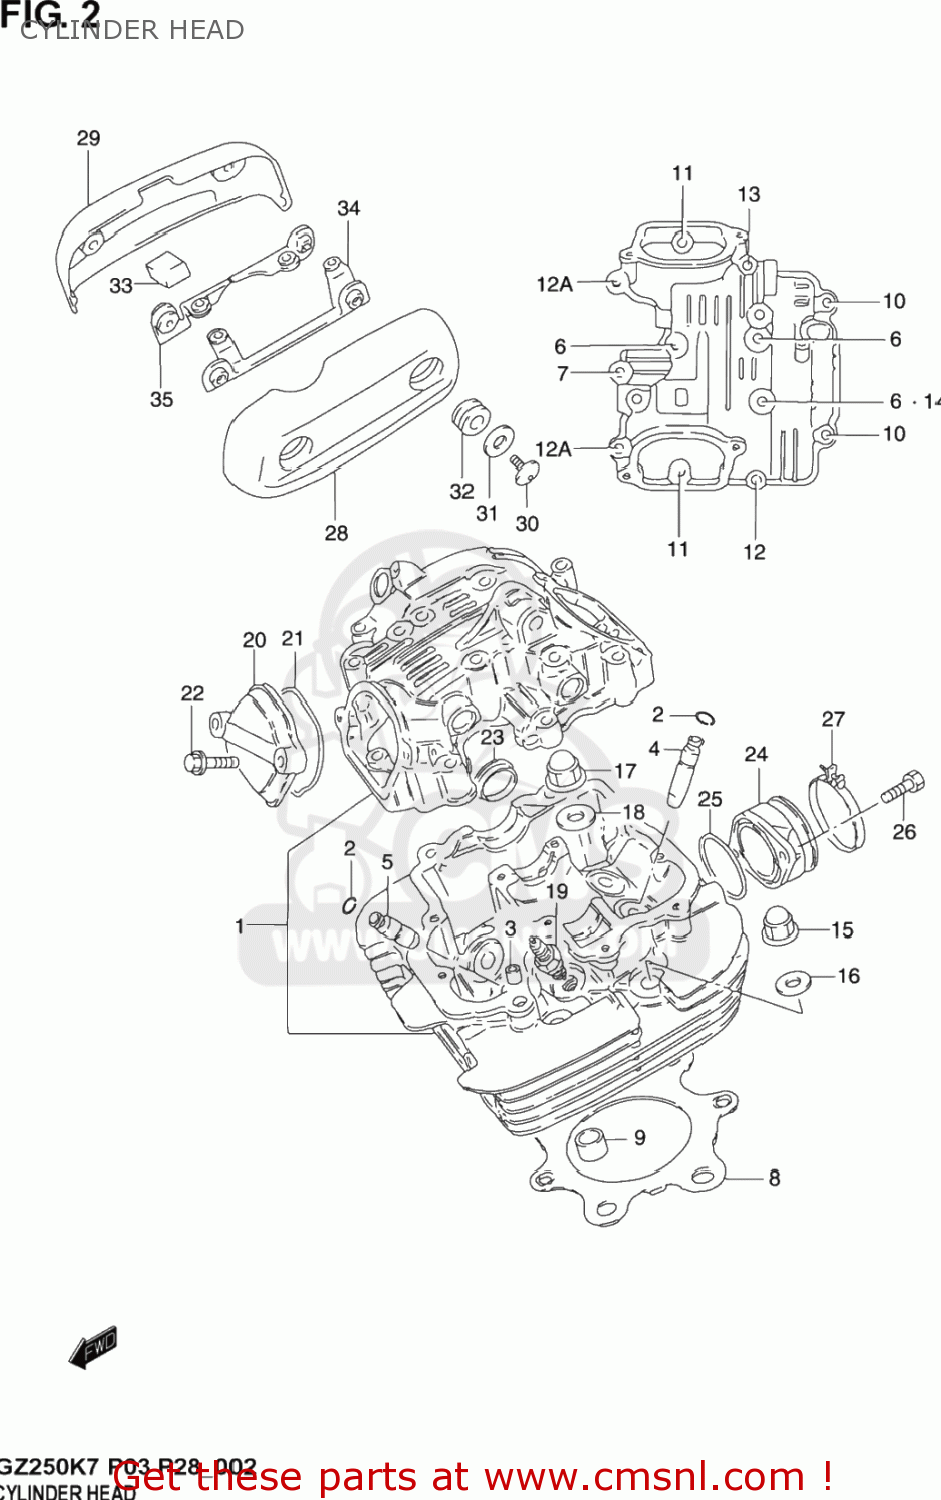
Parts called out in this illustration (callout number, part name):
1	HEAD ASSY,CYLINDER
2	RING,SNAP
3	PIN(6.2X8X11)
4	GUIDE,INTAKE VALVE
5	GUIDE,VALVE
6	BOLT
7	BOLT
8	GASKET,CYLINDER HEAD (NAS)
9	PIN
10	BOLT(6X120)
11	BOLT
12	BOLT (6X45)
12A	BOLT
13	BOLT
14	GASKET(5.8X13X1.2) (NAS)
15	NUT
16	WASHER(10.5X22X2.3)
17	NUT
18	GASKET(10.5X22X2) (NAS)
19	PLUG,SPARK(DR8EA)
20	CAP,INSPECTION
21	O RING(D:2.4,ID:23)
22	BOLT
23	PLUG(OD:30)
24	PIPE,INTAKE
25	O RING(D:2.4,ID:39.7)
26	SCREW ,6X16
27	CLAMP
28	CAP,CYLINDER HEAD COVER,L
29	CAP,CYLINDER HEAD COVER,R
30	BOLT
31	WASHER(6.5X24X1.6)
32	CUSHION
33	DAMPER,HEAD CAP,R
34	BRACKET,HEAD CAP,L
35	BRACKET,HEAD CAP,R
